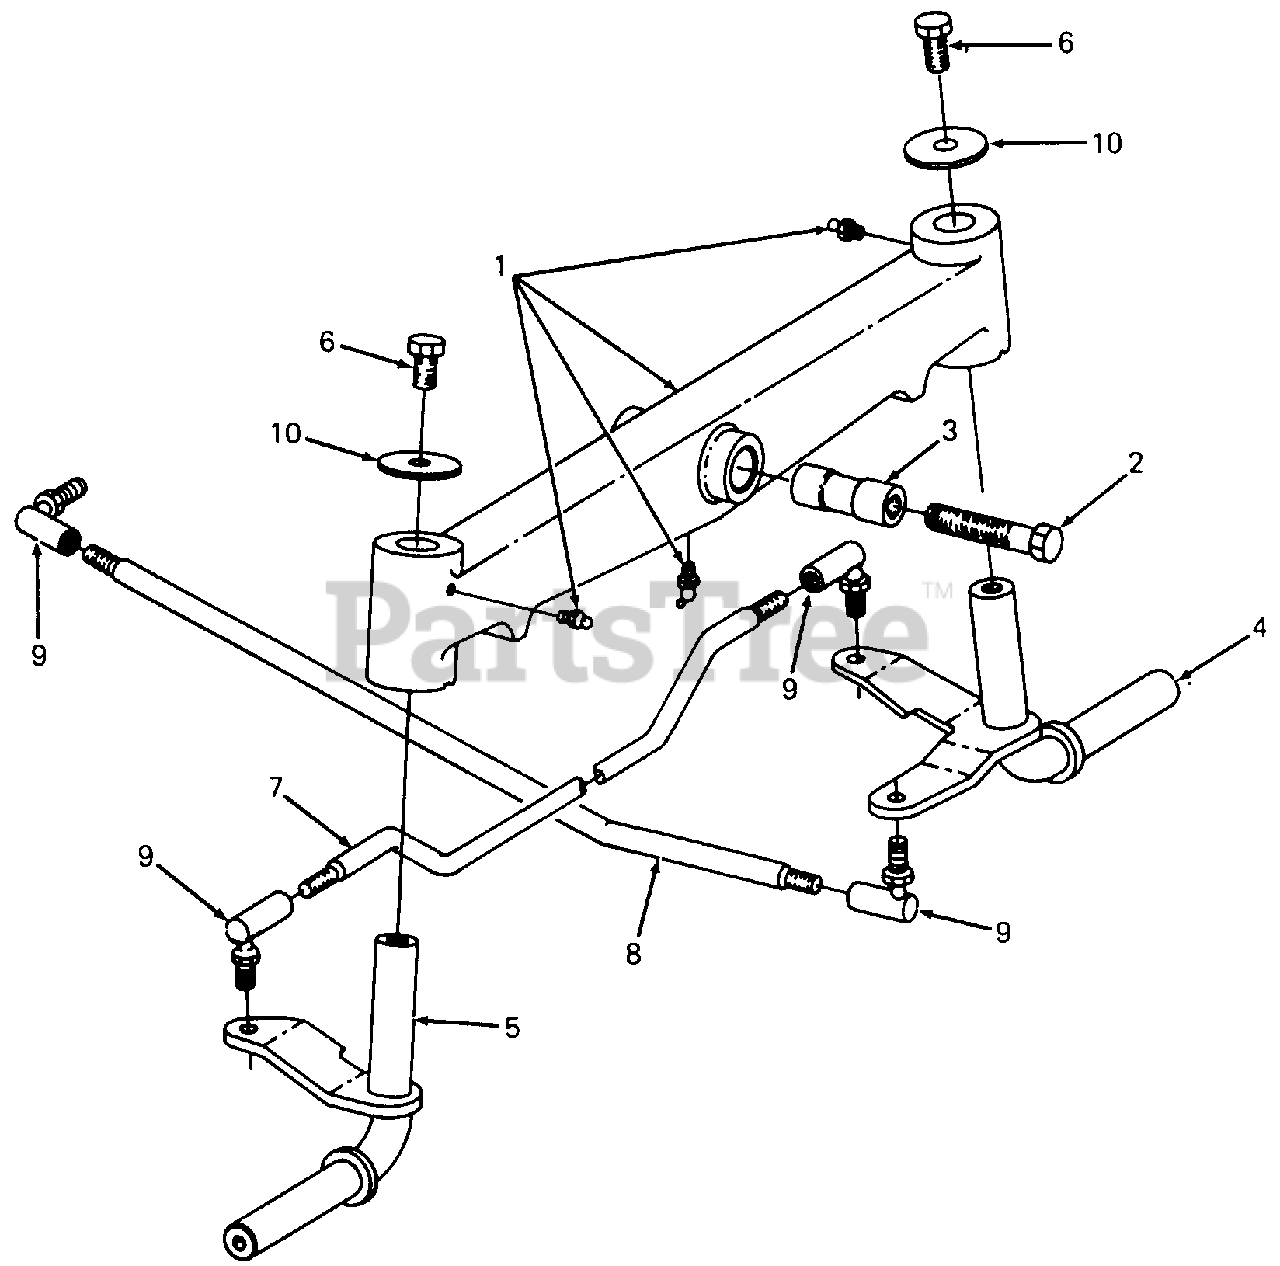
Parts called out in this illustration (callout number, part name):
1	Axle, Front
2	Bolt, 1/2-20 X 4.0 Long GR 5
3	Bushing, Axle Pivot
6	Bolt, 3/8-16 X 3/4 Long GR 5
7	Link,Drag
8	Link, Drag
9	Joint, 3/8-24 Ball Type G
10	Washer, .406 X 1.50 X 11 ga.
